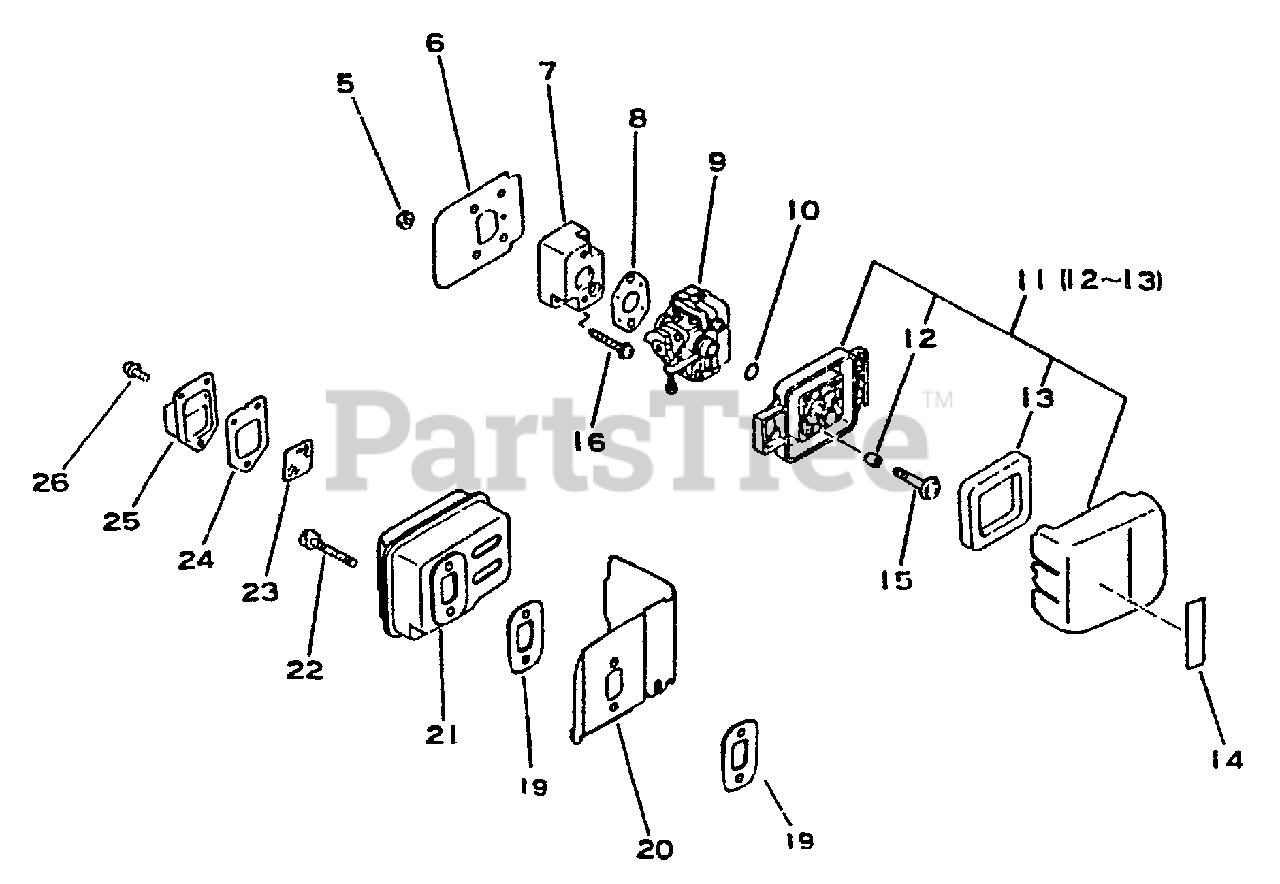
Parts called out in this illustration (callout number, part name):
5	NUT M5
6	HEAT SHIELD, INTAKE
7	INSULATOR, INTAKE
8	GASKET, INTAKE
9	CARBURETOR
10	O-RING 15
11	AIR FILTER ASSY
12	SLEEVE
13	FILTER, AIR
15	SCREW 5×64
16	SCREW 5×22
19	GASKET, EXHAUST
20	COVER, EXHAUST
21	MUFFLER
22	BOLT 5×55
23	SCREEN, SPARK ARRESTER
24	GASKET, EXHAUST
25	LID, MUFFLER
26	SCREW 4×10
